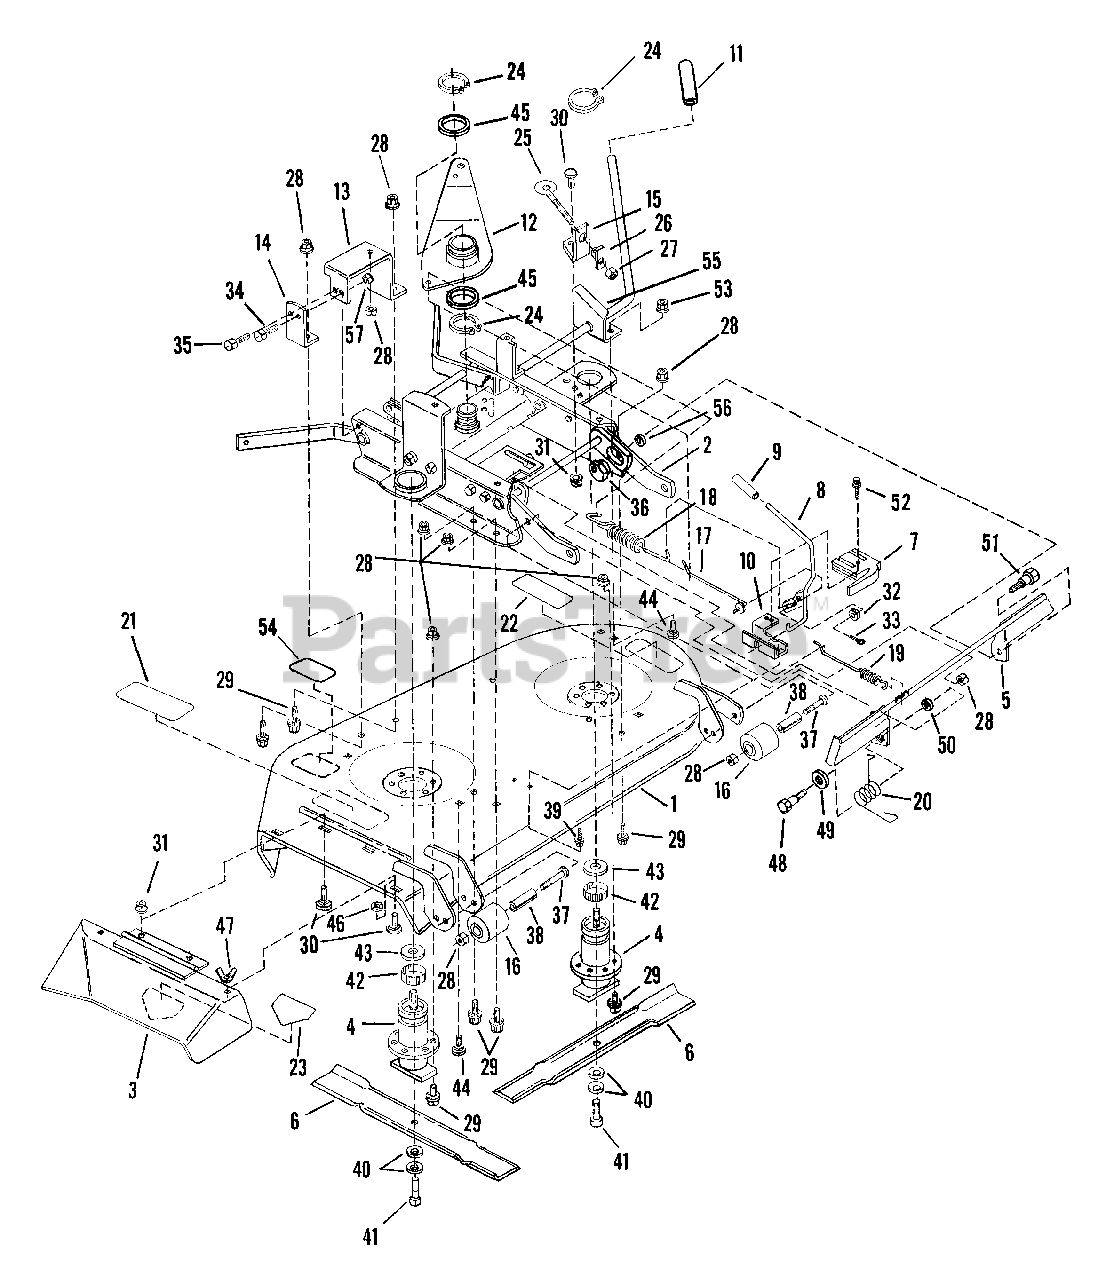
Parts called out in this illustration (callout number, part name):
1	ASSEMBLY, Deck
2	ASSEMBLY, Rail
3	ASSEMBLY, Side Chute
4	ASSEMBLY, Spindle
5	ASSEMBLY, Pedal
6	BLADE, 21"
7	SWITCH
8	ENGAGE LEVER
9	GRIP, Handle
10	BRACKET
11	GRIP, Lever
12	IDLER ARM
13	SUPPORT, Idler
14	BRACKET
15	ANCHOR
16	ROLLER
17	ROD, Idler
18	SPRING, Belt
19	SPRING, Latch
20	SPRING, Pedal
21	DECAL, Caution (Rotating Blades)
22	DECAL, Caution (Rotating Blades)
23	DECAL, Danger (Keep Hands & Feet Away)
24	RING, 2" External Retaining
25	EYE-BOLT
26	T-NUT
27	NUT, 1/4-20 Hex
28	NUT, Hex Lock 3/8-24
29	SCREW,3/8-24x3/4" Hex Head Cap
30	BOLT, 5/16-18x5/8" Carriage
31	NUT, Hex Flange 5/16-18 Lock
32	WASHER, 1/4 Flat
33	PIN, Cotter 3/32x3/4
34	SCREW, 3/8-16x3/4" Hex Head Cap
35	SCREW, 3/8-16x1" Hex Head Cap
36	ECCENTRIC, Leveling
37	SCREW, 3/8-24x3 3/4" Hex Head Cap
38	SPACER
39	SCREW, 1/4-20x5/8 Self-Tapping
40	WASHER, Cone
41	SCREW, 3/8-24x1" Hex Head Cap
42	RING, Tolerance
44	BOLT, 3/8-16x3/4" Carriage
45	WASHER, 2" I.D.
46	RETAINER, 5/16 Bolt
47	NUT, 5/16-18 Wing
48	BOLT, 3/8-24x9/16" Shoulder
49	WASHER, 1/2 Flat
50	WASHER, 3/8" Flat
51	BOLT, 3/8-24x3/4" Shoulder
52	SCREW, #10-32x1" Self-Tapping
53	NUT, 3/8-16 Hex Lock
54	PLATE, Model Number
55	BRACKET, Height Indicator
56	WASHER, 3/8 Internal Tooth Lock
57	NUT, 3/8-16 Hex Lock
